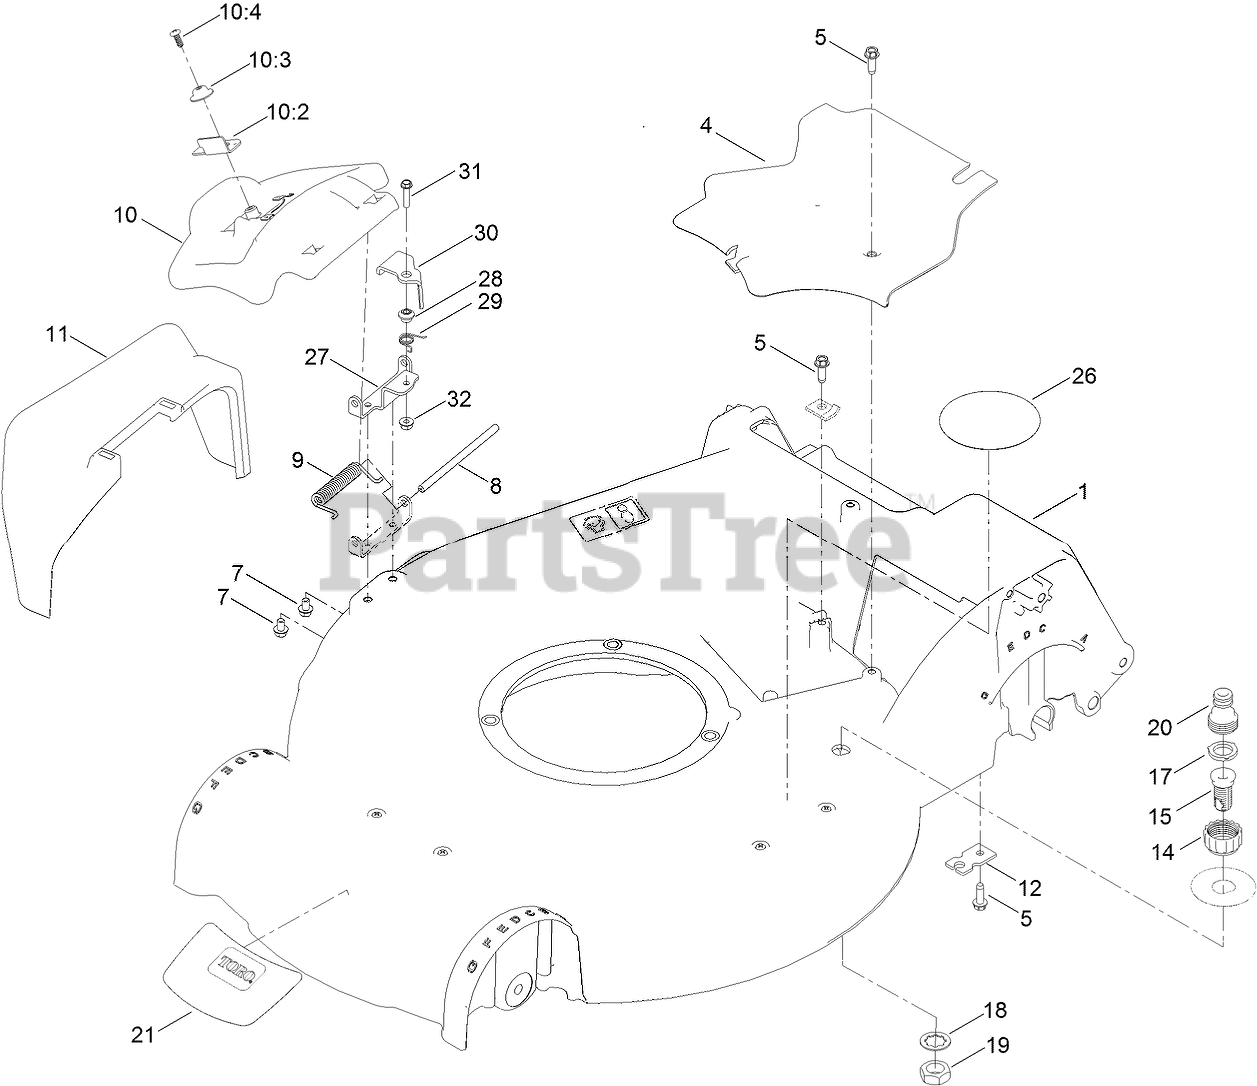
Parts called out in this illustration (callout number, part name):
1	HOUSING ASM
4	COVER-BELT
5	SCREW-HWHTF
9	SPRING-TORSION
10	DISCHARGE DOOR ASM
10:2	LATCH-DOOR
10:3	CAP-DOOR
10:4	SCREW-PPH
11	CHUTE-DISCHARGE, SIDE
12	BRACKET-CABLE, TRACTION
14	COUPLING-HOSE, WASHOUT PORT
15	PORT-WASHOUT
17	WASHER-SEAL, WASHOUT PORT
18	WASHER-LOCK, INT TOOTH
19	NUT-JAM
20	ADAPTER-CONNECT, QUICK
21	DECAL-DECK
26	DECAL-POS
27	BRACKET-LOCKOUT
28	SPACER
29	SPRING-TORSION
30	LEVER-LOCKOUT
31	SCREW-HWH
32	NUT-HEX FLANGE
